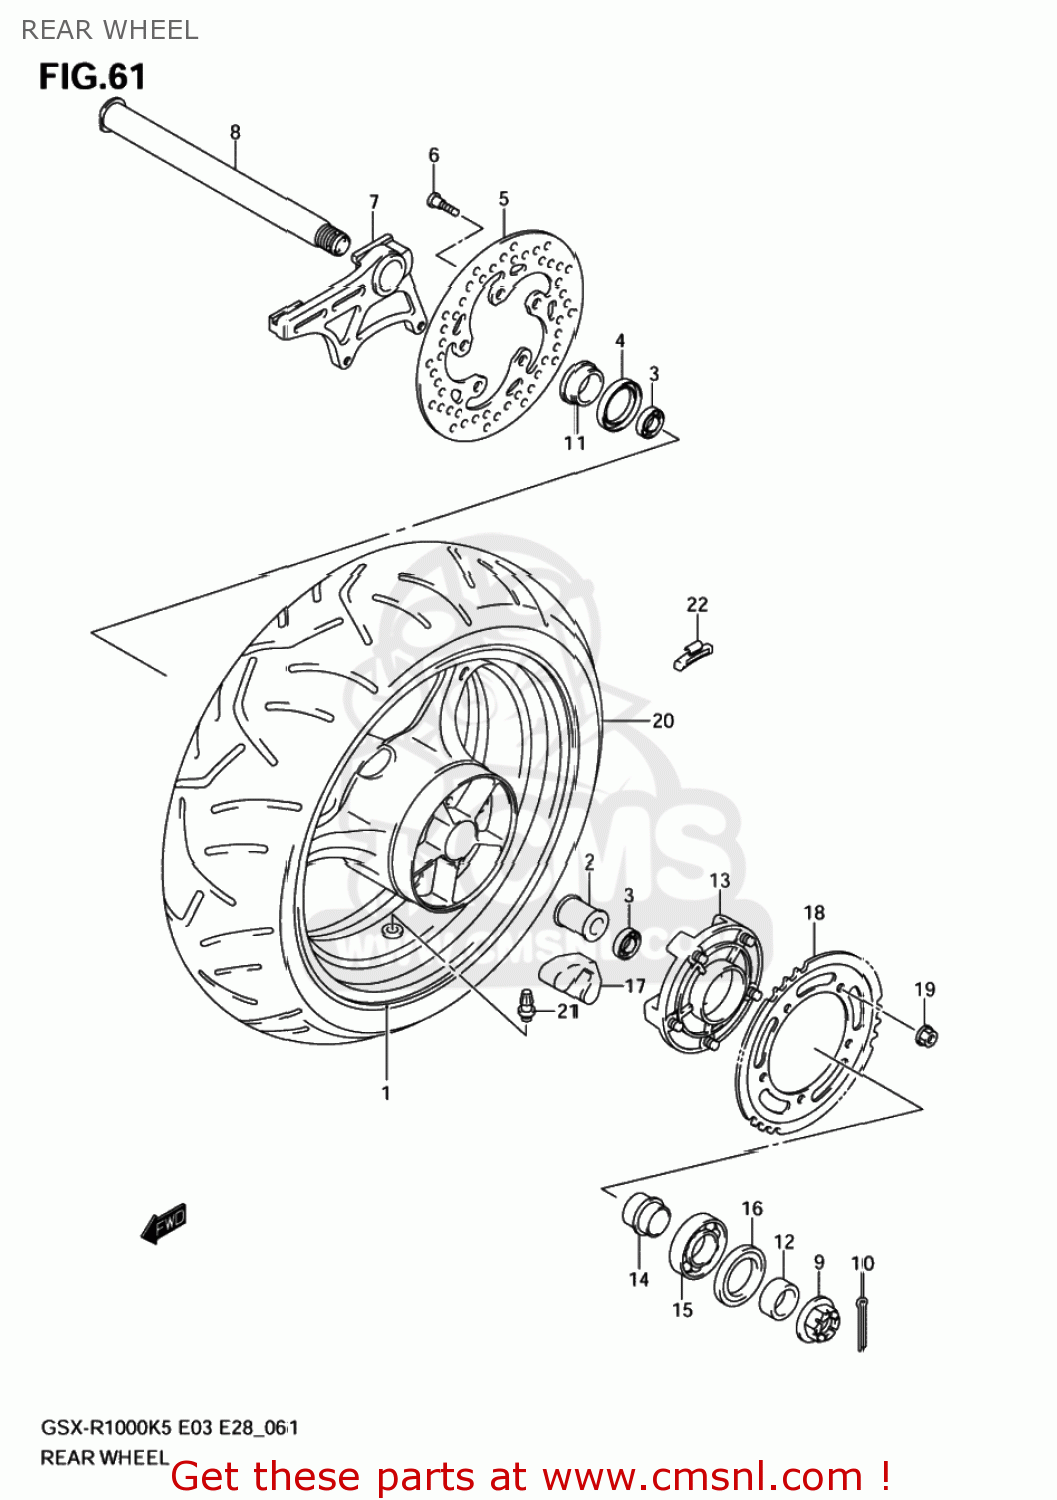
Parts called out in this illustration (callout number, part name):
1	WHEEL,RR(17M/CXMT6.00)
2	SPACER,RR WHEEL BEARING
3	BEARING(28X52X12)
4	SEAL,OIL(37X52X8)
5	DISC,RR BRAKE
6	BOLT(8X21)
7	BRACKET,RR CALIPER
8	AXLE,RR
9	NUT
10	PIN, COTTER
11	SPACER,RR AXLE,R
12	SPACER,RR AXLE,L
13	DRUM,RR SPROCKET
14	RETAINER,RR SPROCKET DRUM
15	BEARING
16	SEAL,OIL(39X65X7)
17	ABSORBER,RR HUB SHOCK
18	SPROCKET,RR(42T-530)
19	NUT
20	TIRE,RR(190/50ZR17M/C 73W)
21	VALVE ASSY,WHEEL RIM(TR412)
22	WEIGHT,WHEEL BALANCE 10G
